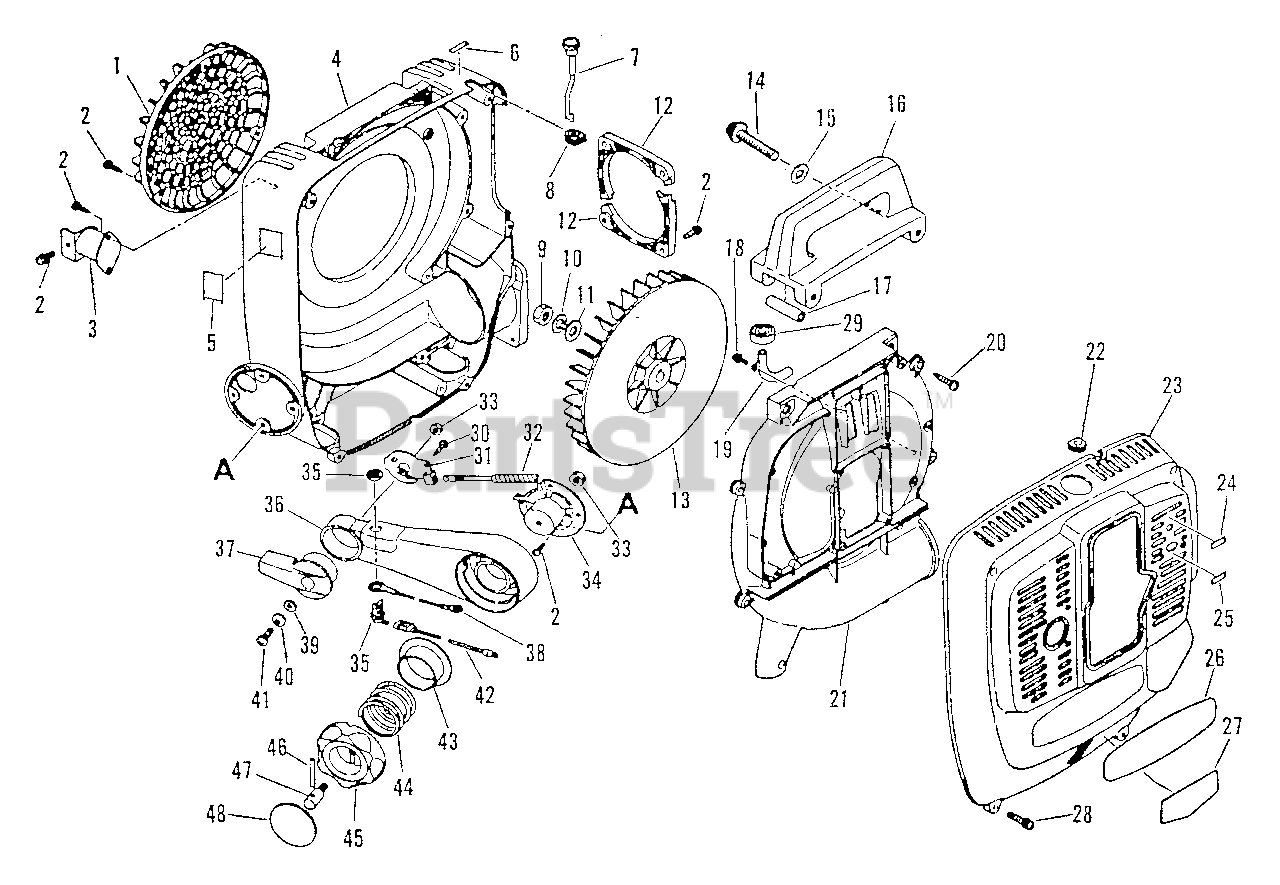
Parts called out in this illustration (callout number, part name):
1	SHIELD, DEBRIS
2	SCREW 5×14
4	COVER, FAN - INNER
5	LABEL - CAUTION
6	LABEL - CHOKE
7	ROD, CHOKE
10	WASHER, SPRING 10
11	WASHER 10.5×18×1.6
12	RETAINER
13	FAN
14	SCREW 6×70
15	WASHER 6.5×11.5×0.8
18	SCREW 4×10
19	PIPE, INTAKE
20	SCREW 5×25
21	COVER, FAN - OUTER
23	COVER
24	LABEL, CAUTION - IDLE
25	LABEL - CAUTION
26	LABEL - ECHO
27	LABEL - MODEL
28	SCREW 5×20
30	SCREW 4×10
31	BRACKET, THROTTLE
33	NUT, HEX M6
34	PLATE
35	SWITCH, ON-OFF
36	BRACKET, THROTTLE LEVER
37	TRIGGER, THROTTLE
38	LEAD - GROUND
39	WASHER 6.5×11.5×0.8
41	SCREW 6×20
43	SEAT, SPRING
45	KNOB
48	LABEL
